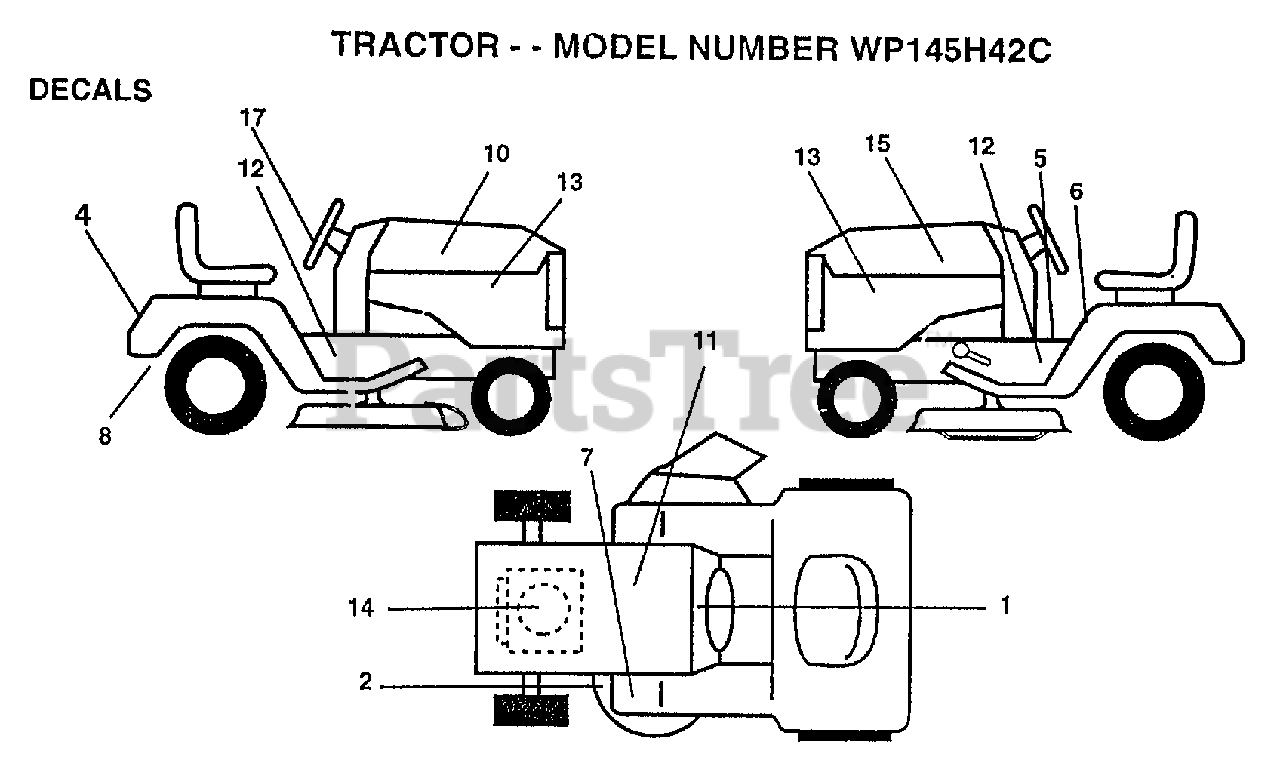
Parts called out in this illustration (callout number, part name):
1	"DECAL-INST,OPER"
2	DECAL
4	DECAL, FENDER LOGO
5	DECAL BRAK PARK
6	"DECAL DANGER,FEND"
8	DECAL DRAWBAR LH
10	DECAL.HOOD.RH
11	DECAL.BATRY.3-3908
12	DECAL CHAS 42 HYD
13	DECAL.WP145H42A
14	DECAL, ENGINE
15	DECAL.HOOD.LH
17	DECAL, INSERT
